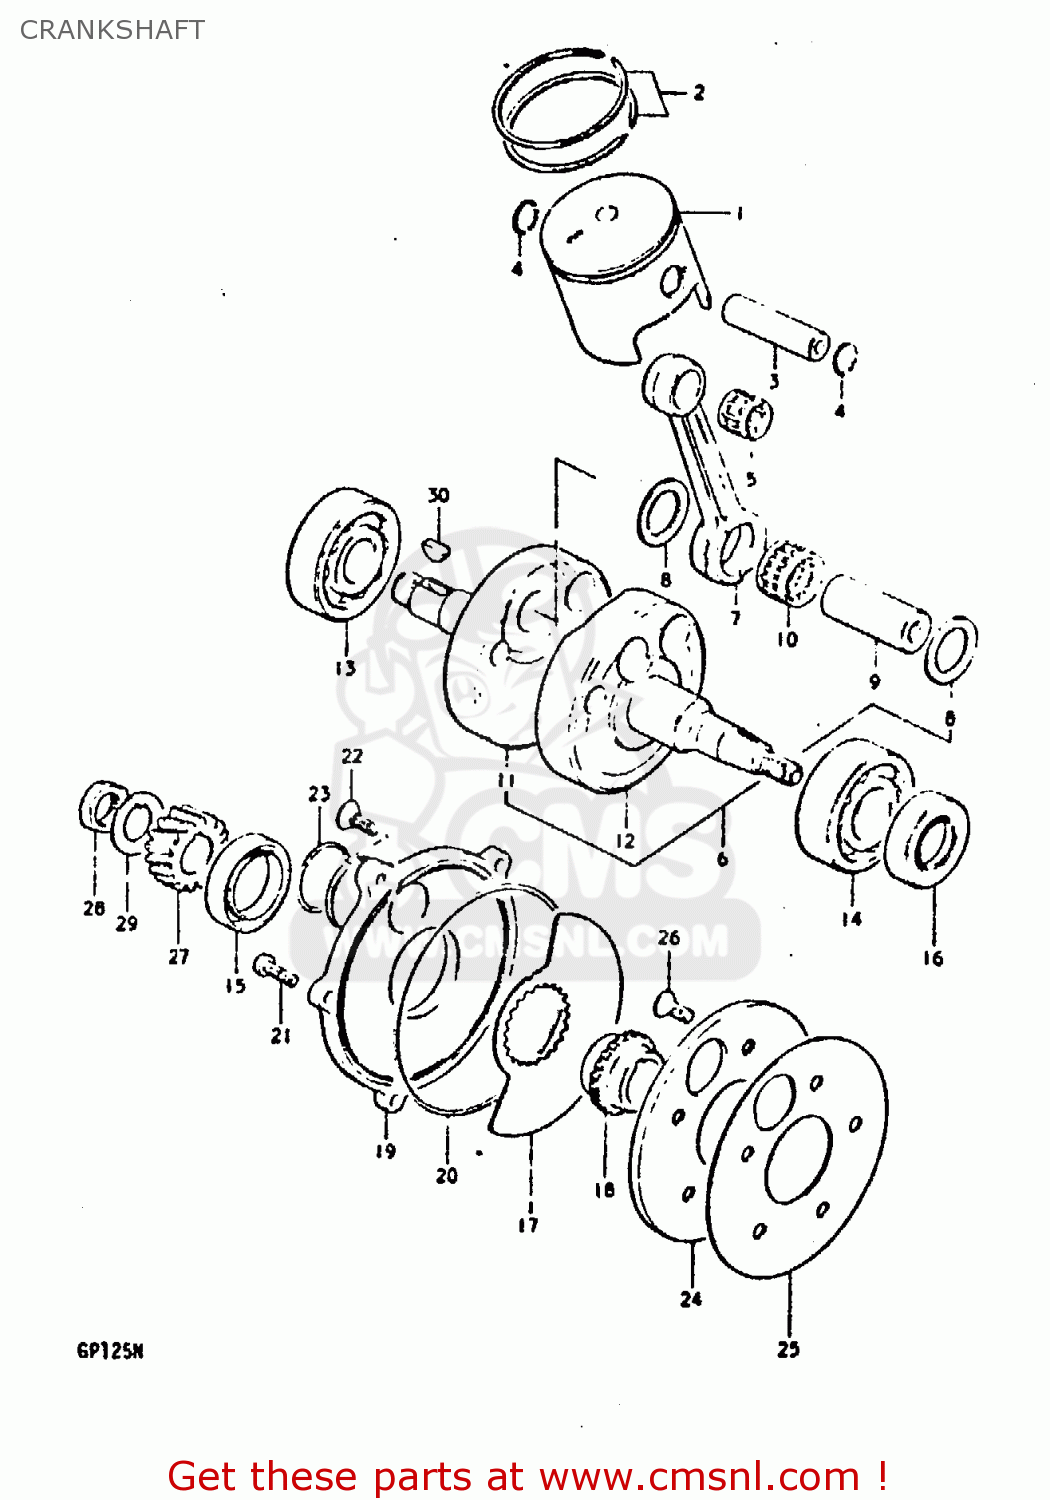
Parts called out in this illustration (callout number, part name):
1	PISTON
2	RING SET,PISTON
3	PIN,PISTON
4	RING,SNAP 14MM
5	BEARING
6	CRANKSHAFT ASSY
7	CONNECTING ROD
8	WASHER(19X32X1)
9	PIN,CRANK
10	BEARING(19X25X16)
11	CRANKSHAFT,R
12	CRANKSHAFT, LH
13	BEARING
14	BEARING
15	SEAL,OIL(30X44X7)
16	OIL SEAL
17	PLATE,CRANKSHAFT VALVE
18	GUIDE, VALVE
19	SEAT, OUTER VALVE
20	O RING(D:2,ID:108.6)
21	SCREW
22	SCREW
23	O RING(D:2.4,ID:28.7)
24	SEAT,CRANKCASE INNER VALVE
25	GASKET, INNER VALVE SEAT (NAS)
26	SCREW
27	GEAR,PRIMARY DRIVE
28	NUT
29	WASHER
30	KEY
